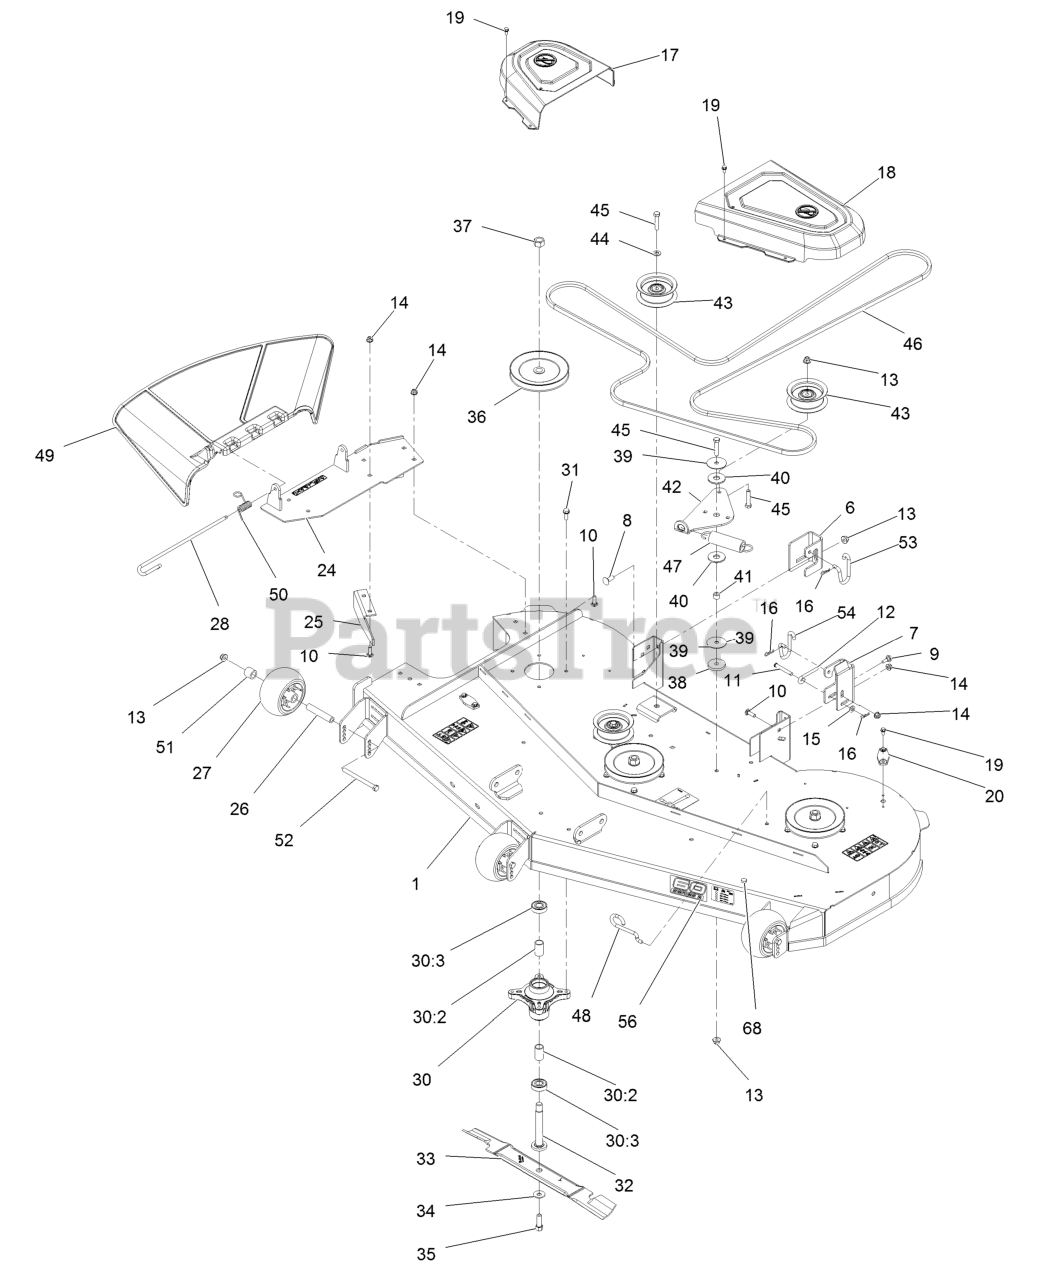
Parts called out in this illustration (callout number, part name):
1	60 Inch Deck And Decal ASM
6	Bracket-Hanger, RH
7	Bracket-Hanger, LH
8	Bolt-Carriage 3/8-16 X 1
9	Screw-HH Flg 1/4-20 X 3/4 Tf
10	Bolt-Carriage 5/16-18 X 1 Sp
11	Pin-Clevis
12	Rod-Level, Deck
13	Nut-Nyloc 3/8-16 Flg
14	Nut-Nyloc 5/16-18 Flg
15	Washer-5/16 SAE
16	Hairpin-Cotter
17	Cover-Belt, RH
18	Cover-Belt, LH
19	Screw-HWH 1/4-20 X 1/2 Taptite
20	Cover-Washout Port
24	Pivot-Deflector
25	Baffle-Cutoff
26	Tube-Spanner
27	Roller-Scalp, Anti
28	Pin-Chute
30	Spindle ASM
30:3	Bearing-Ball
31	Screw-HWH 3/8-16 X 7/8 Taptite
32	Shaft-Spindle
33	Blade-Hi Flow, 20.5 Inch
34	Washer-Spring Disc
35	Screw-HH 7/16-20 X 1.36 Gr8
37	Nut-Hex 5/8-18
38	Washer-Plain
40	Washer-Friction, Composite
42	Arm-Idler
43	Pulley-Idler, Flat
44	Washer-3/8 SAE
45	Screw-HH 3/8-16 X 1 3/4
46	Belt
47	Spring-Extension
48	Hook-Return, Spring
49	Deflector-Discharge
50	Spring-Torsion
51	Spacer-Axle, Rear
52	Screw-HH 3/8-16 X 4-1/2
53	Link-Retention, Deck (RH)
54	Link-Retention, Deck (LH)
56	Decal-Series 2 60
68	Screw-HH 5/16-18 X 5/8
